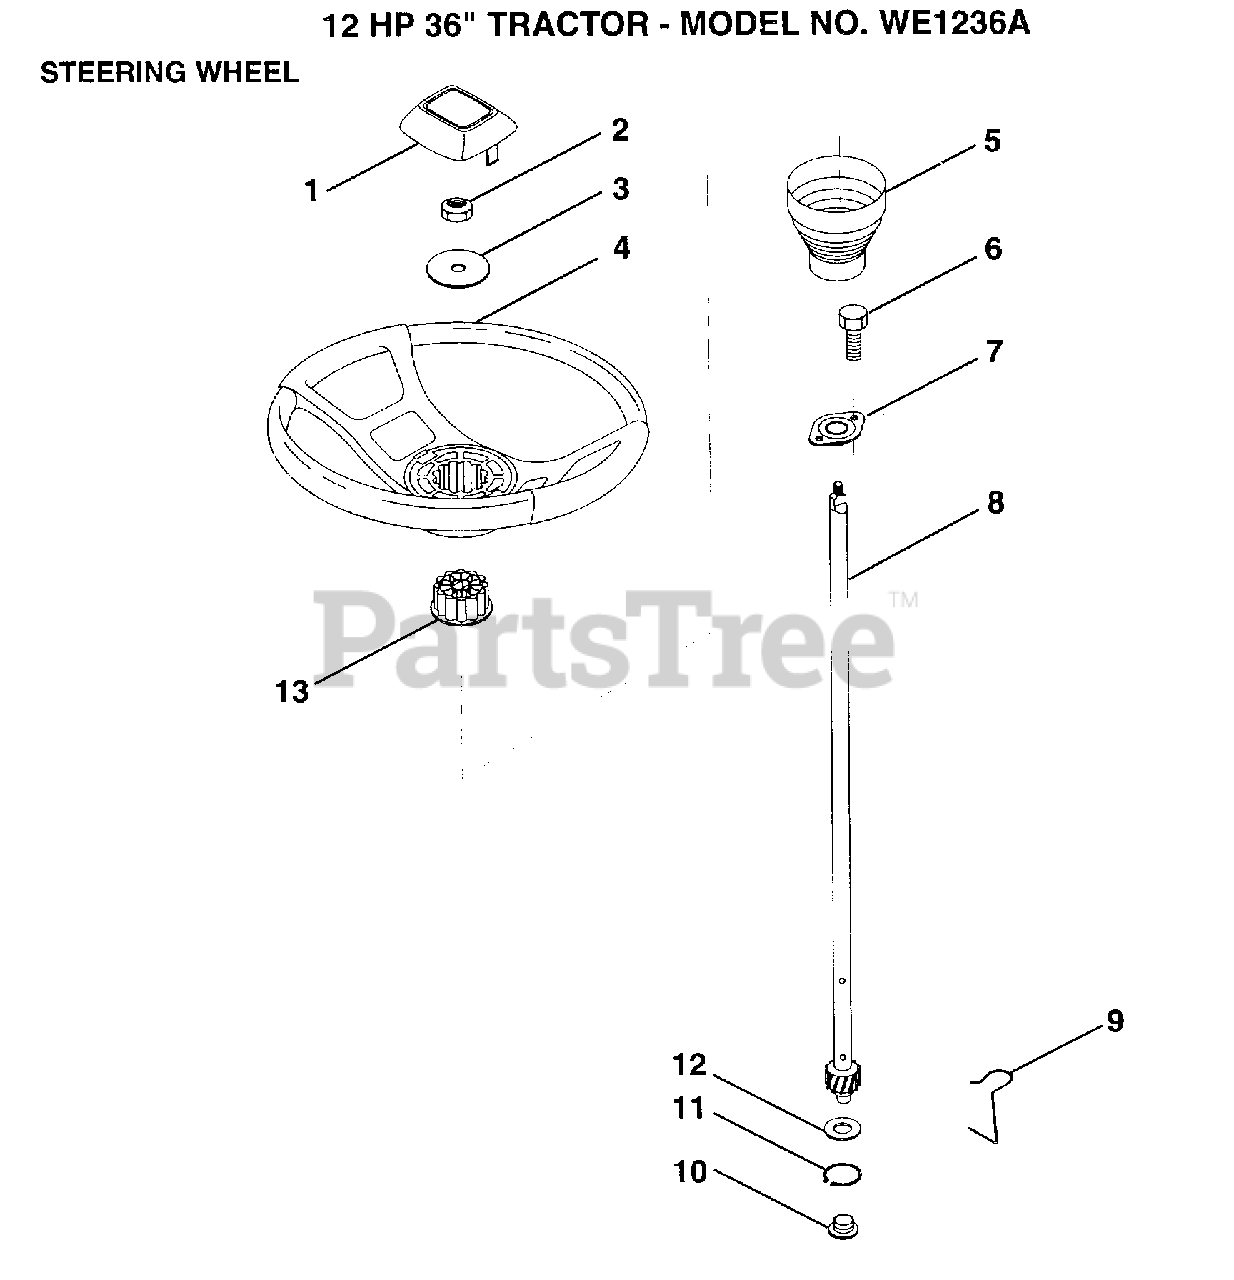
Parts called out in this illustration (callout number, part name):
1	ST WHL INSERT CAP
2	GRIPCO NUT
3	WASHER T
5	SLEEVE STEERING
9	STEERING CLIP
10	BUSHING STEER LWR
11	RING
12	WASHER LT
13	ADAPTER-WHEEL LT
